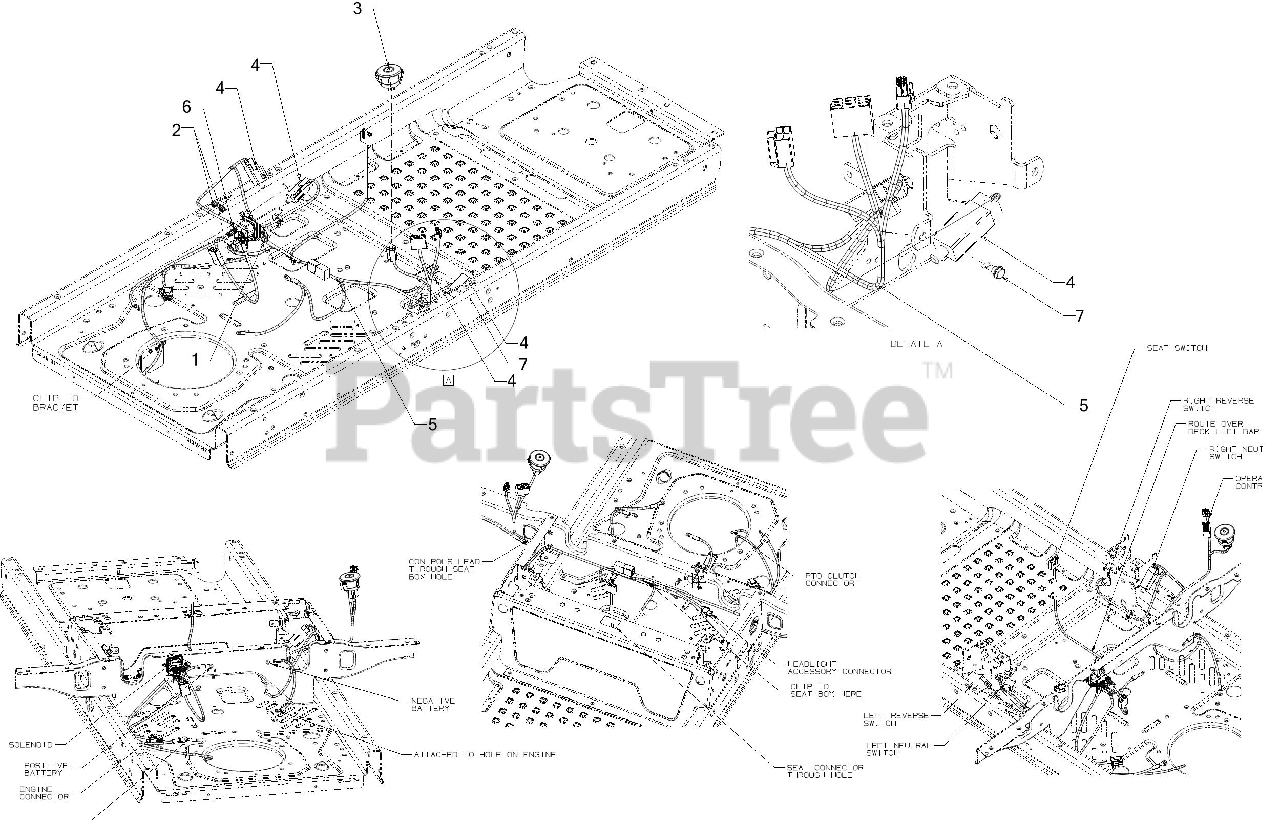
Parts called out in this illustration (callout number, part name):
1	SCREW 1/4-20X.625
2	FLANGE LOCK NUT
3	KEY SWITCH 3 POSITION
4	INTERLOCK SWITCH (NO/NC)
5	MAIN HARNESS
6	SOLENOID-12V 100A
7	SHOULDER SCREW
